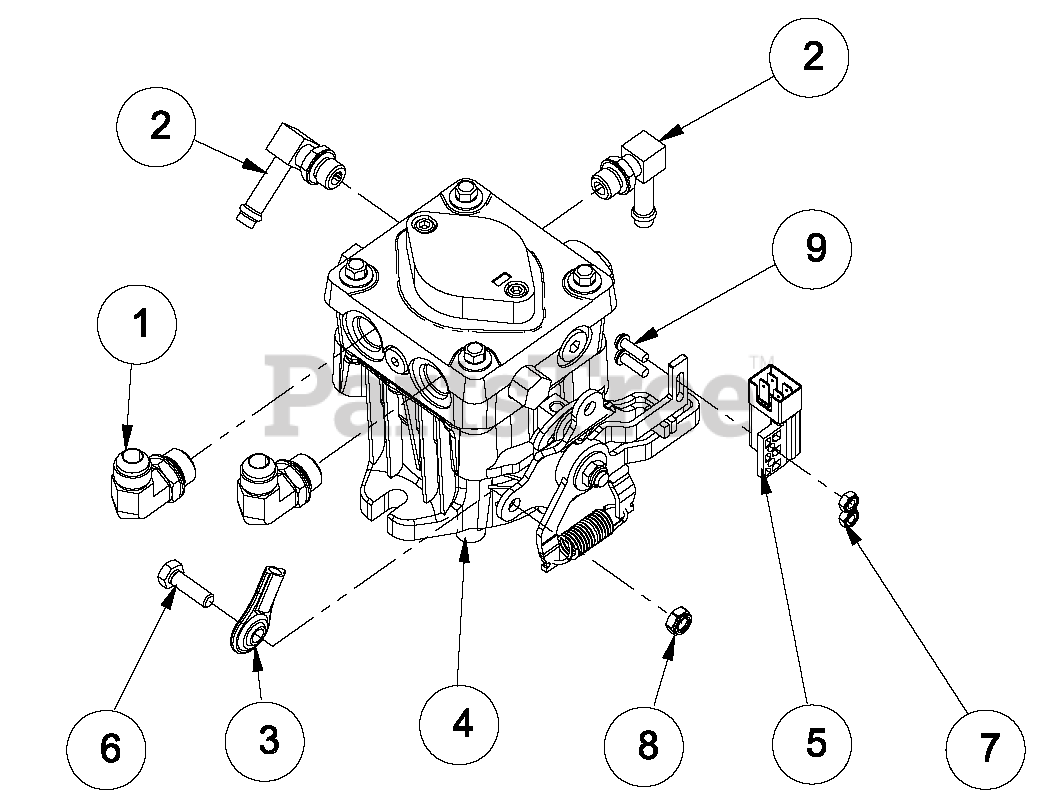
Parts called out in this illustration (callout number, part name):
1	FTG, ADP JIC-ORB 6801-08-08
2	FTG, 90 9/16 MOR X 3/8 HOSE
3	ALIGNABALL, 5/16-24 RH THD
4	PUMP, RH HYDRO PG-1GRQ
5	SWITCH, PLUNGER DP - N.O. - N.C.
6	BOLT, 5/16-18 X 1.00 HEX 5 Y
7	LOCKNUT, 10-24 NYLOC Y
8	LOCKNUT, 5/16-18 NYLOC Y
9	SCREW, 10-24 X .625 PAN PHL MAC Y
